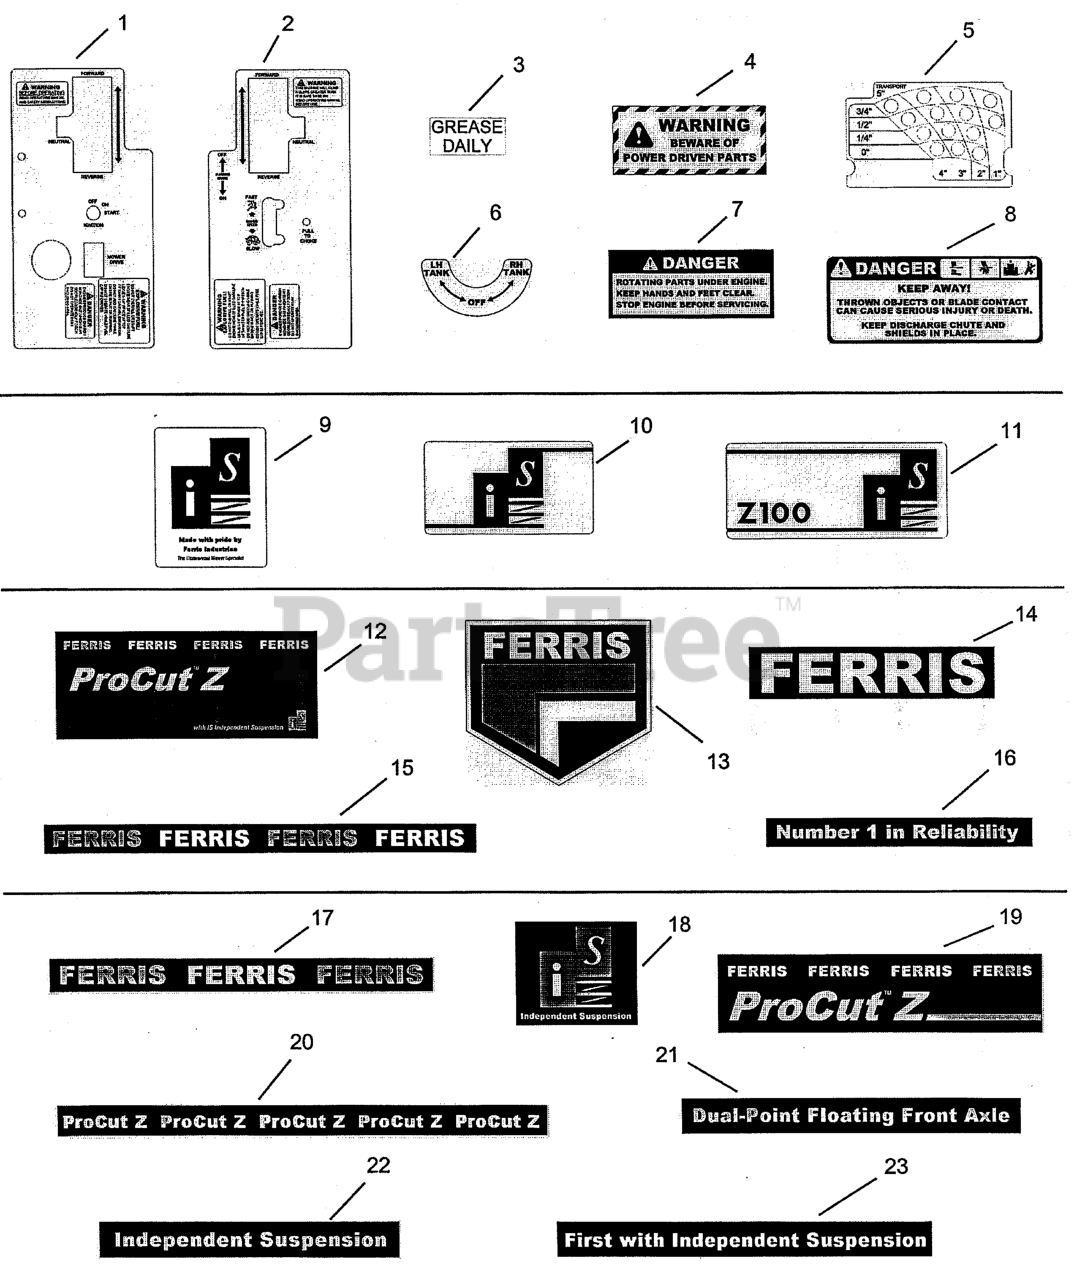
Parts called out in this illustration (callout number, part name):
1	DECAL, CONTROL PANEL-LEFT, NET
2	DECAL, Control Panel, Right
3	DECAL, Grease Daily
4	DECAL, Warning
5	DECAL, Deck Height
6	DECAL, Fuel Shut Off
7	DECAL, Danger, Rotating
8	DECAL, DANGER DO NOT OPERATE W/O DEFLECT
9	DECAL, I.S. Logo
10	DECAL, I.S.
11	DECAL, I.S. Z100 Logo
12	DECAL, ProCut Z-I.S.
13	DECAL, Ferris Logo, 6-3/8"
14	DECAL, Ferris Text
15	DECAL, Ferris Text Long
16	DECAL, Number One In Reliability
17	DECAL, Ferris Text
18	DECAL, I.S. Logo
19	DECAL, ProCut Z
20	DECAL, ProCut Z Text
21	DECAL, Dual Point Floating
22	DECAL, Independent Suspension
23	DECAL, First w/ Independent Suspension
